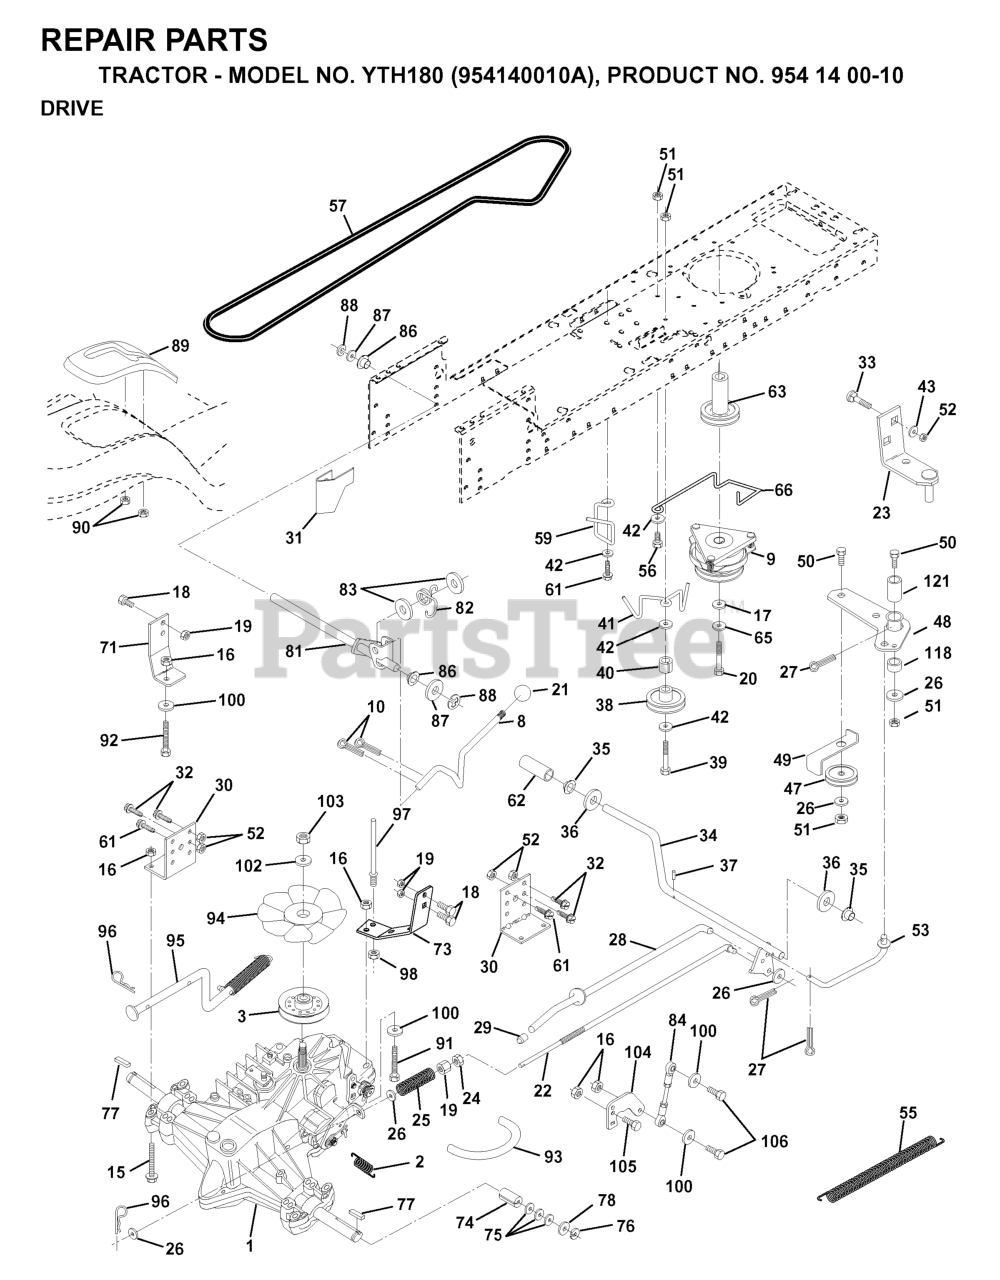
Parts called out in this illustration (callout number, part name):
1	TRANSAXLE ASSEMBLY
2	SPRING BRAKE
3	PULLEY, TRANSAXLE
8	ROD SHIFT FENDER
9	CLUTCH.ELECT.CVX.105 FT/LB.
10	PIN COTTER
15	BOLT HEX 5/16-18 GR 5
16	NUT.71038.31-18.HEX.NYLOCK
18	BOLT
19	NUT
20	BOLT HEX
21	KNOB.DELUXE.(PISTOL.GRIP).BLAC
22	ROD BRAKE HYDRO
23	BRACKET ASM MTG
24	NUT
25	SPRING ROD LT
26	WASHER
27	COTTER PIN
28	ROD BRAKE PARK LT
29	PLUNGER CAP
30	BRACKET TRANSAXLE
31	KEEPER BELT LH
32	BOLT
33	RP BOLT 5/16-18 X3/4 ZN/YEL GR
34	SHAFT, FOOT PEDAL
35	BEARING.NYLON
36	WASHER LT
37	DRIVE PIN
38	PULLEY.IDLER.FLAT
41	KEEPER, BELT IDLER
42	WASHER
43	WASHER T
47	IDLER PULLEY
48	BELLCRANK ASSEMBLY
49	RETAIN BELT
50	BOLT
52	LOCKNUT
53	LINK, CLUTCH LT
55	SPRING, RETURN LT
57	DRIVE BELT, LTH & YTH TRACTORS
59	KEEPER CENTER SPAN
61	SCREW
62	COVER, PEDAL (1 2)
63	PULLEY CLU ELEC
65	LOCKWASHER
66	KEEPER BELT ENGINE
71	STRAP LH TORQUE
73	STRAP TORQUE RH HYDRO
74	SPACER SPLIT
77	SQUARE KEY
81	SHAFT ASSY
82	SPRING,TORSION
83	WASHER
84	ROD.TIE.BALL.4.75
86	BUSHING.STEERING.ROD LTB-WSL
89	CONSOLE SHIFT
90	NUT.PUSH.3/16
91	BOLT.FIN HEX 5/16-18UNC X2 1/4
92	HEX BOLT
93	LINE FUEL HYD 4"
94	FAN 7" HYDRO
95	CONTROL ARM, BYPASS HYDRO
96	RETAINER M
97	KEEPER BELT RH
100	WASHER M
103	NUT.HEX.1/2-20
104	CONTROL ARM
106	BOLT.5/16-18X1-1/4 FULL.THREAD
118	SPACER BELLCRANK
121	NYLINER CLUTCHING
